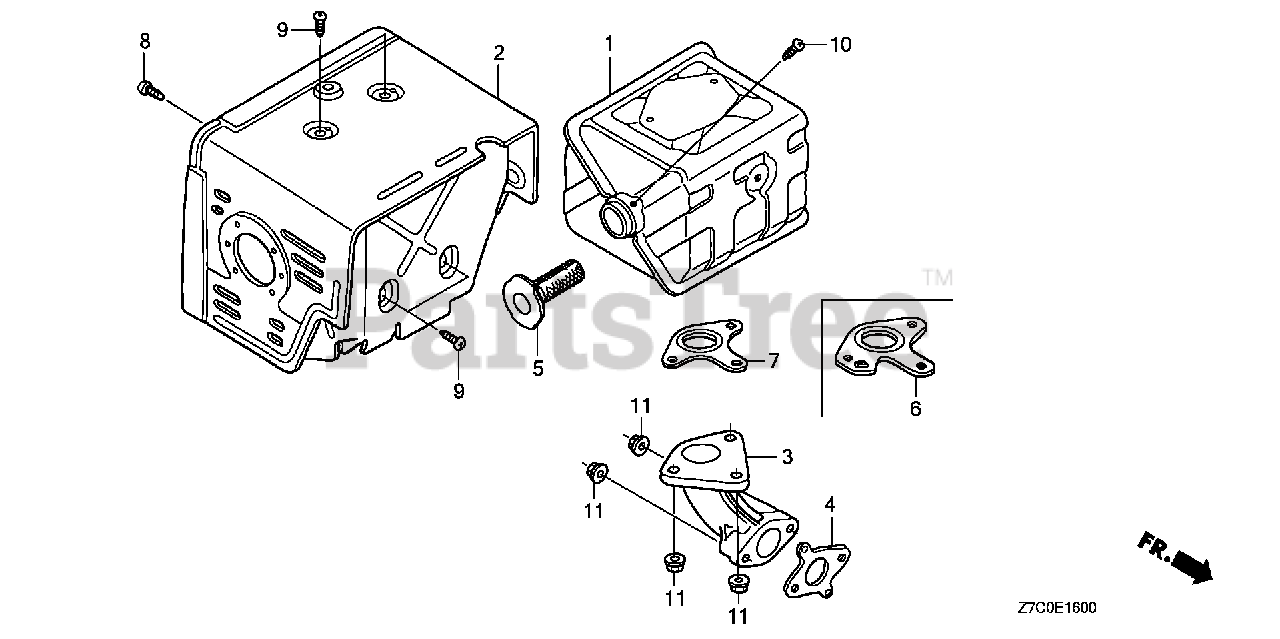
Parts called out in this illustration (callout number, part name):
1	MUFFLER (100DB)
2	PROTECTOR, MUFFLER
4	GASKET, EX. PIPE
5	ARRESTER, SPARK
6	GASKET, MUFFLER (ARRESTER) (NIPPON LEAKLESS)
7	GASKET, MUFFLER (NIPPON LEAKLESS)
7	GASKET, MUFFLER (THAI LEAKLESS)
8	SCREW, TAPPING (6X10)
9	SCREW, TAPPING (5X8)
10	SCREW, TAPPING (4X6)
11	NUT, FLANGE (8MM)
